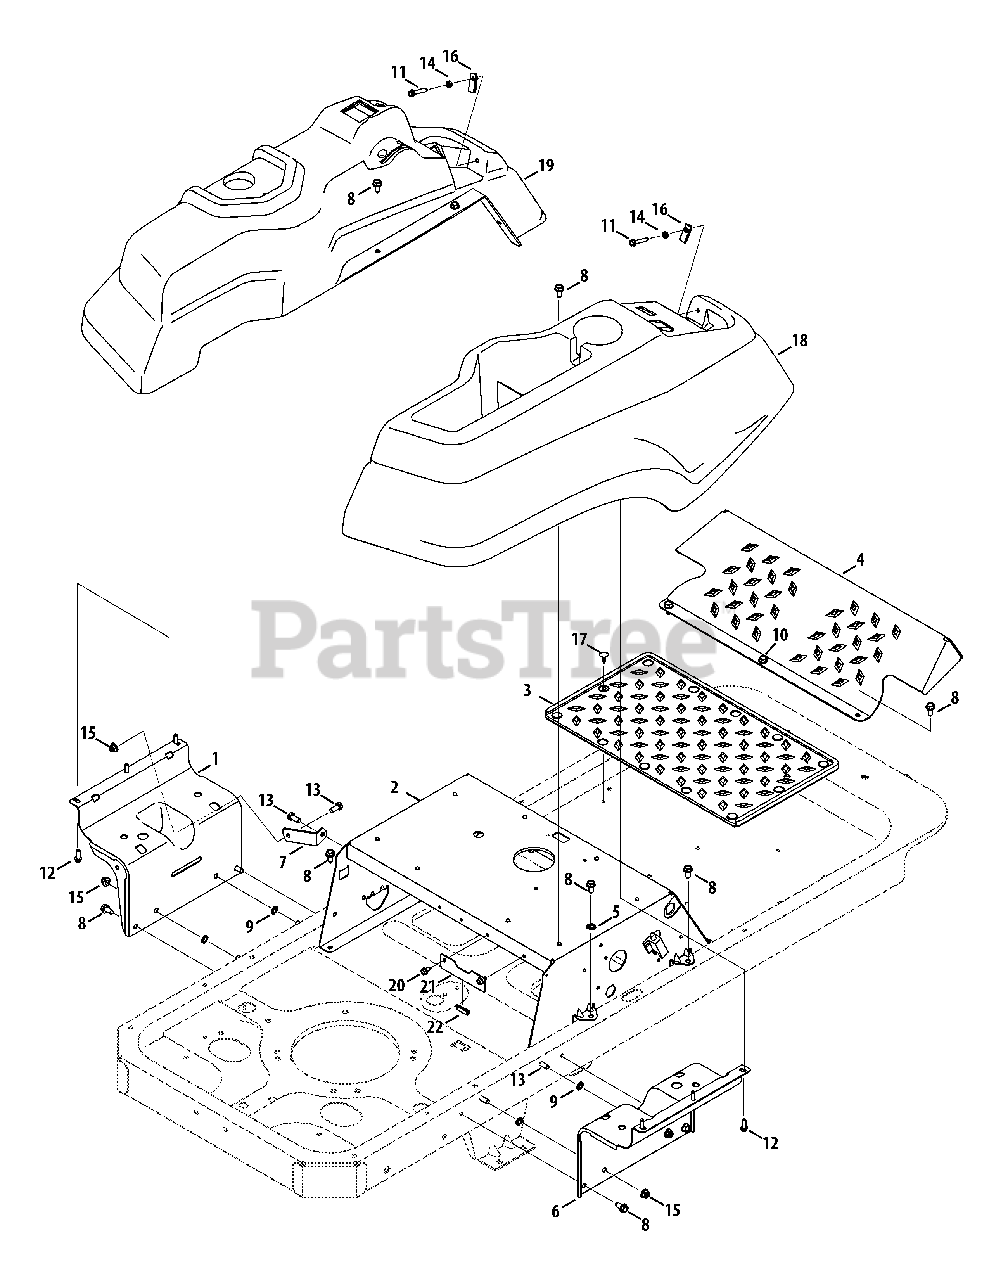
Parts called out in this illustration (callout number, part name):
1	Console Mount Bracket
2	Seat Frame
6	Console Mount Bracket
7	Fuel Tank Support Bracket
8	Hex Washer Screw, 5/16-18 x .750"
9	Speed Nut, .3125"
10	Hex Washer Screw, 5/16-18 x .825"
11	Hex Washer Screw, 1/4-20 x 1.500"
12	Hex Washer Screw, 1/4-15 x .750"
13	Hex Screw, 5/16-18 x .75"
14	Jam Nut, 1/4-20"
15	Flange Lock Nut, 5/16-18"
16	U-Type Nut, 1/4-20"
17	Ratchet Clip, .250"
18	RH Console
20	Hex Screw, 1/4-20 x .5"
21	Battery Hold-Down
22	Trim Strip
